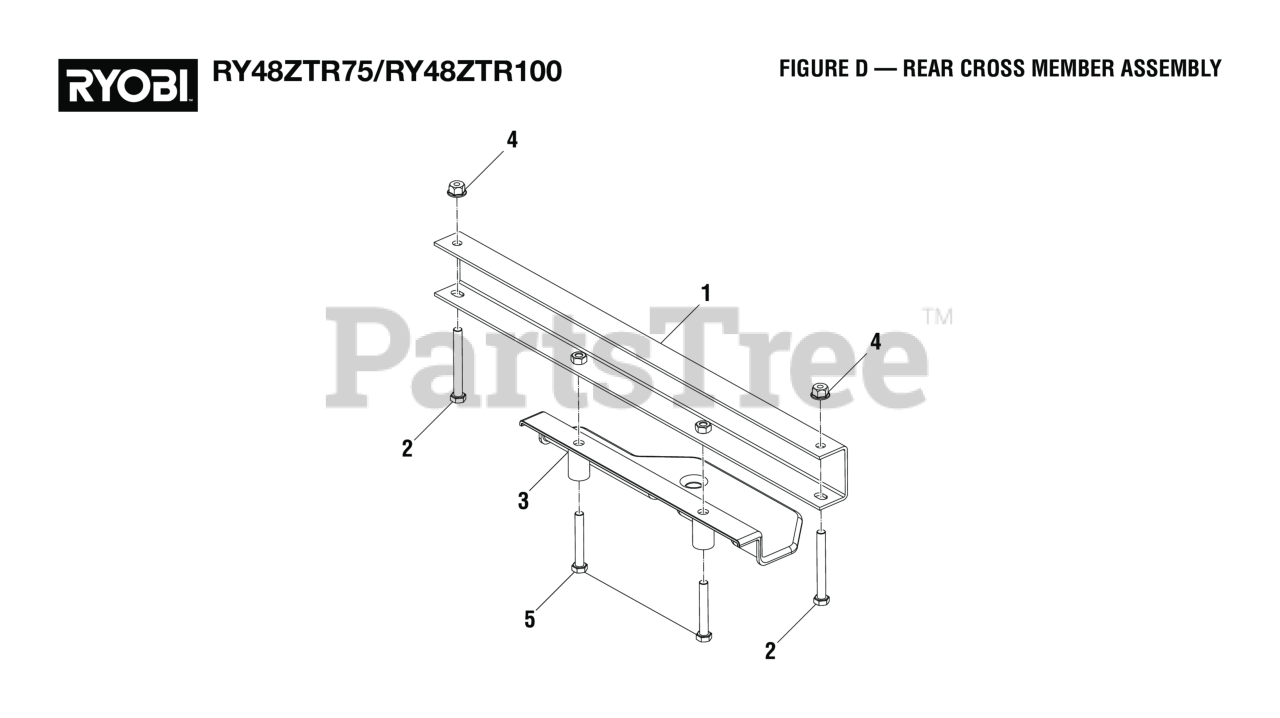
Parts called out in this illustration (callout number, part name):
1	Rear Cross Member, Frame
2	Bolt (M8 x 70 mm, Hex Hd.)
3	Tow Hitch
4	Flange Nut (M8) (For Drive Motor Controller V)
5	Bolt (M8 x 55 mm, Hex Hd.)
